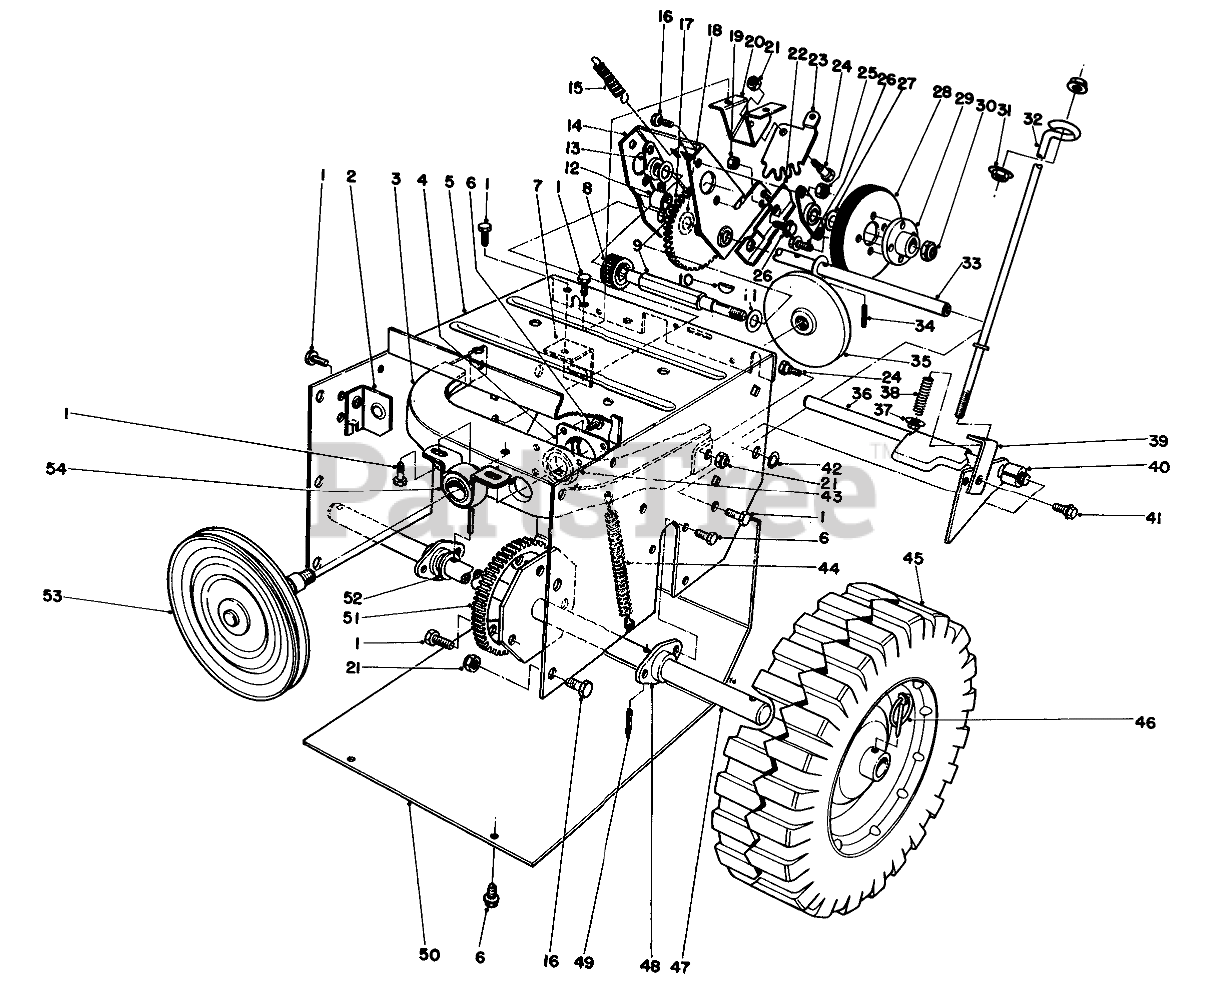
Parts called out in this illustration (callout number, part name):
1	SCREW-HWHTF
2	AUGER CLUTCH MTG FRT
3	"OBS" FRICTION PLT FRAME
4	CUP-BEARING
5	Frame-Traction
6	SCREW
7	BRACKET-MOUNT, REAR
8	PINION
9	SHAFT-WHEEL, FRICTION
10	KEY-WOODRUFF
11	WASHER-FLAT
12	5/8ID X 1LG BUSHING
13	BEARING-WHEEL, FRICTION
14	BRACKET-SLIDING
15	SPRING-TRACTION
16	SCREW-HH
17	Intermediate Gear & Bushing (Incl. Ref. #12)
18	WASHER-SPECIAL
19	NUT-LOCK, NI
20	MOUNT-LEVER
21	NUT-LOCK, NI
22	CAM-RECEIVER
23	GEAR-QUADRANT
24	BOLT-SHOULDER
25	NUT-LOCK, CONE
26	Screw
27	WASHER-THRUST
28	WHEEL-FRICTION
29	HUB-WHEEL, FRICTION
30	NUT-LOCK, NI
31	NUT-HF
32	ROD-TRACTION, LOWER
33	SHAFT-PIVOT
34	PIN-SPRING
35	PLATE-FRICTION
36	Traction Engagement Asm.
37	NUT-LOCK, HHF
38	SPRING
39	BRACKET-TRACTION
40	SPACER
41	SCREW
42	RING-RETAINING
43	BEARING-BALL
44	SPRING-PLATE, FRICTION
45	Wheel
46	PIN-LYNCH
47	AXLE SHAFT WA
48	BEARING-AXLE
49	PIN-SPRING
50	Bottom Cover
51	GEAR-AXLE
52	WASHER-THRUST
53	Pulley & Shaft
54	BUSHING ASM
